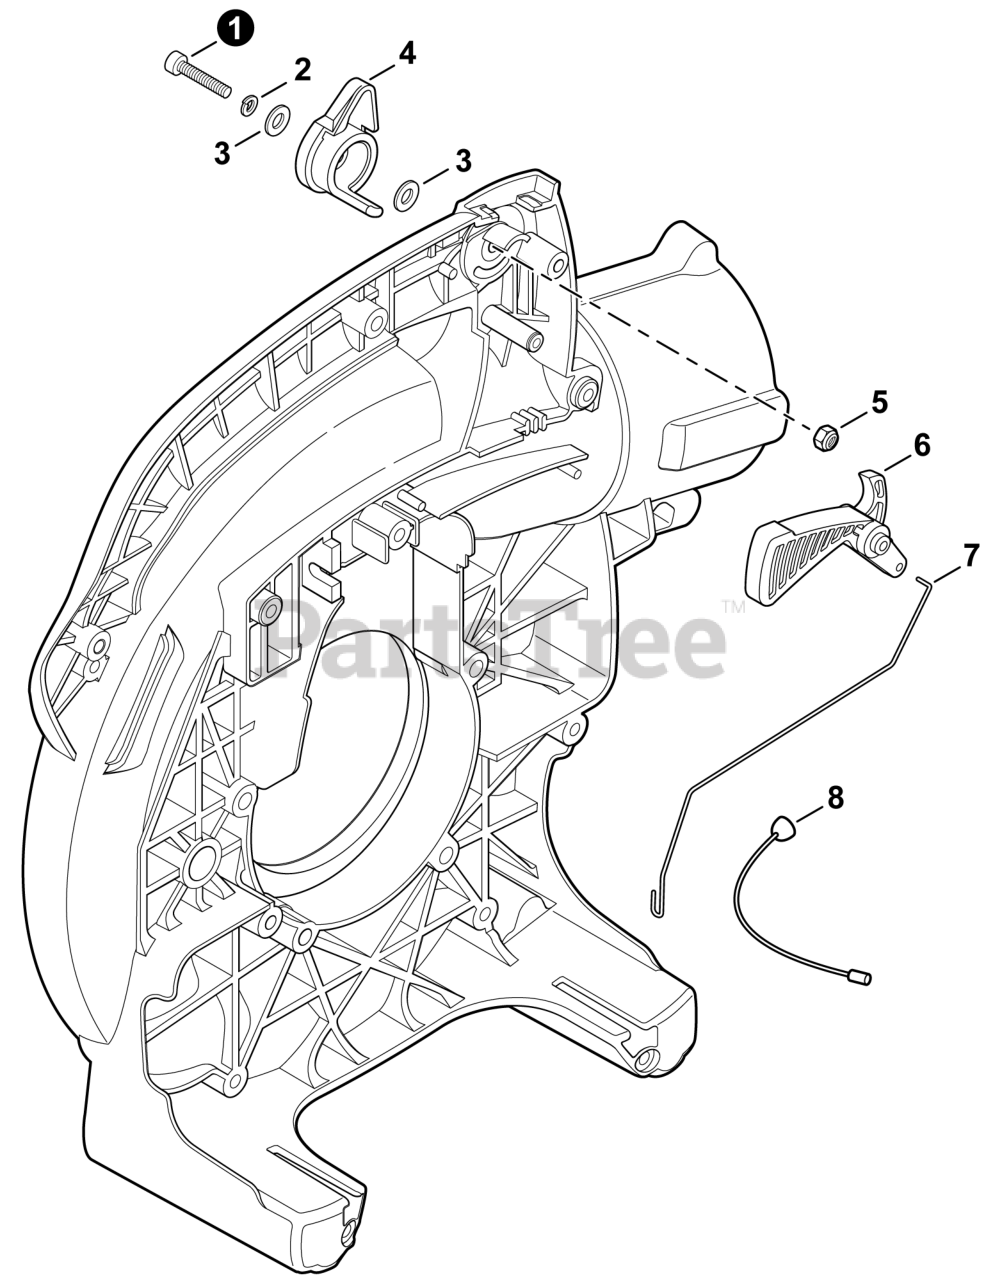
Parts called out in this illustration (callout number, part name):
1	BOLT, TORX 5x25
2	WASHER, SPRING 5
3	WASHER 5.5x12x0.8
4	CONTROL, THROTTLE
5	NUT, LOCK M5
6	TRIGGER, THROTTLE
7	ROD, THROTTLE
8	CABLE, THROTTLE
